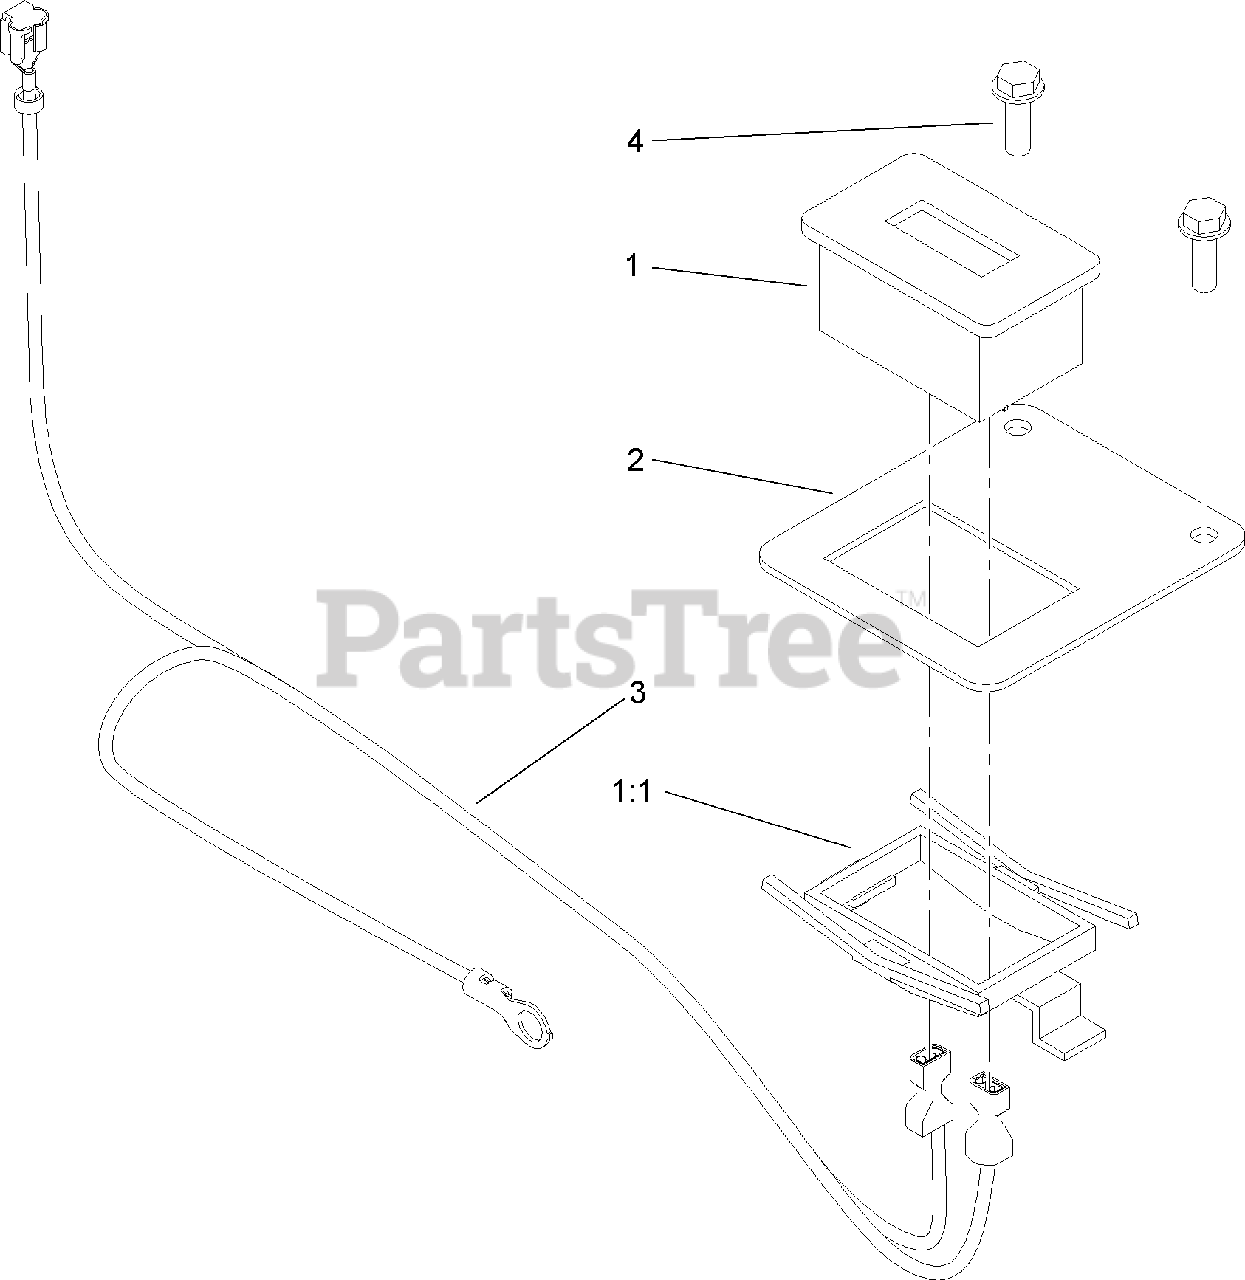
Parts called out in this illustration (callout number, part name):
1	METER-HOUR
1:1	CLIP-MOUNTING
2	BRACKET-HOUR METER
3	HARNESS-WIRING, HOUR METER
4	SCREW-FORMING, THREAD
